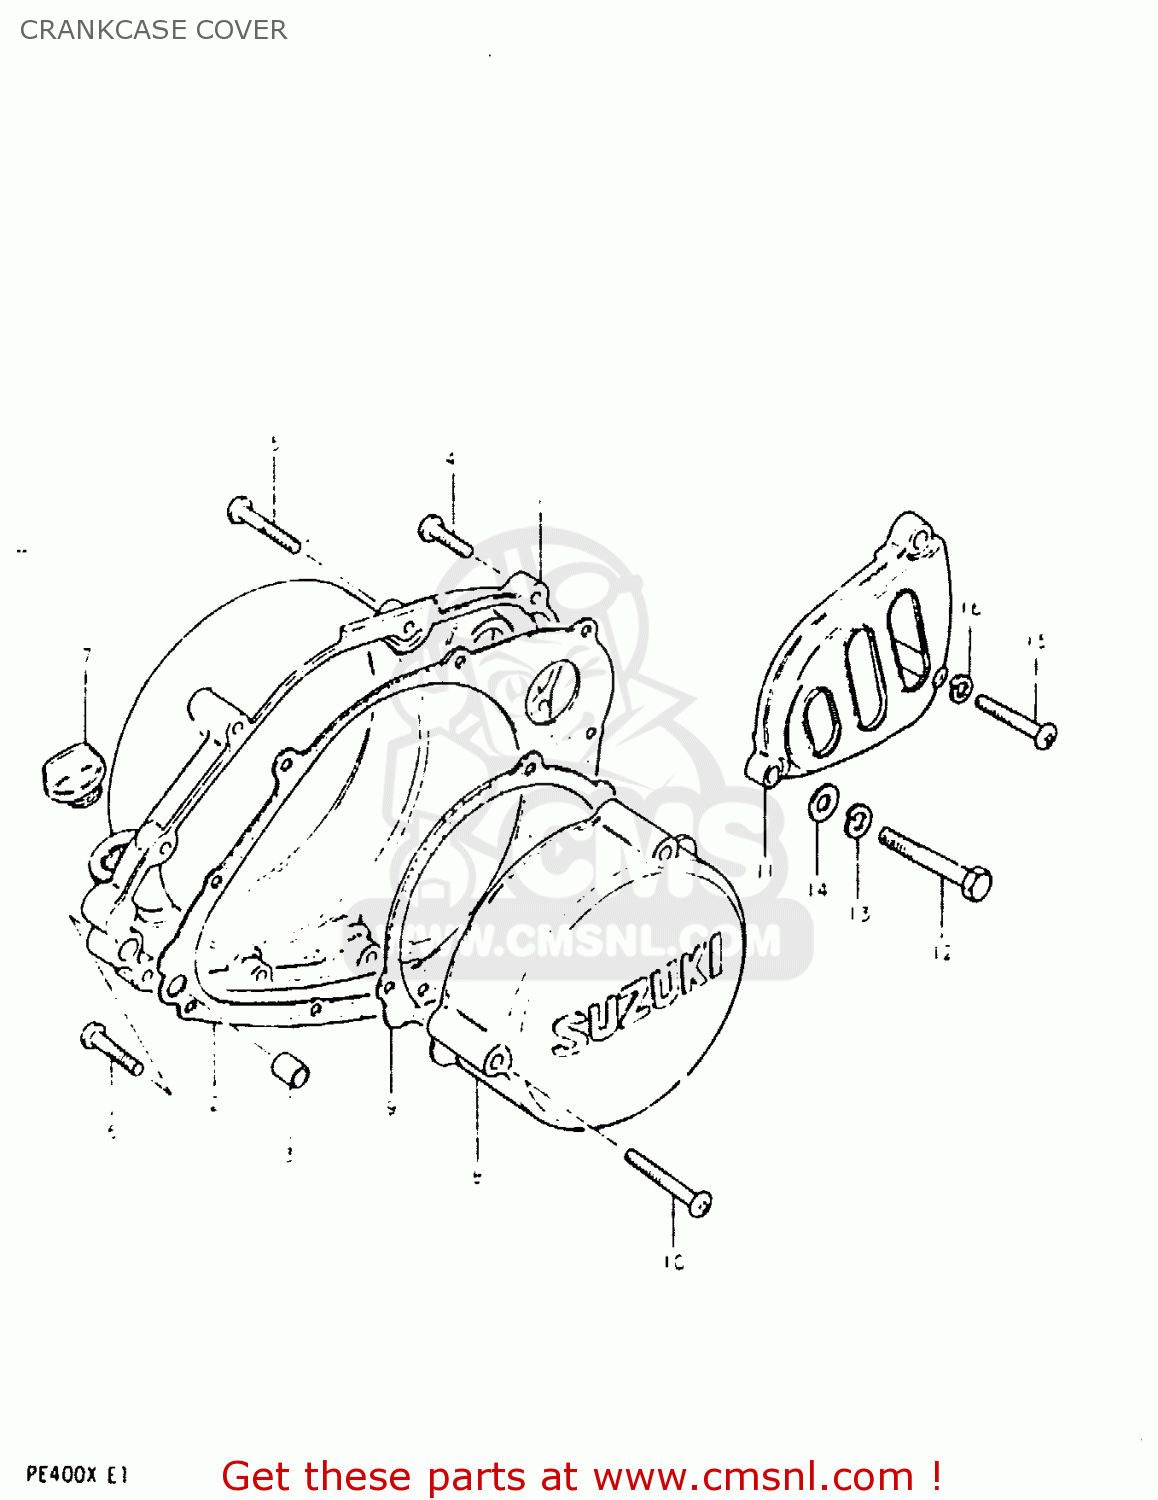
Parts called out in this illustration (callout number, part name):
1	COVER,CLUTCH
2	GASKET,CLUTCH COVER (MCA)
3	PIN
4	SCREW
5	SCREW 6X30
6	SCREW (6X45)
7	PLUG,OIL FILTER
8	COVER,MAGNETO
9	GASKET,MAGNETO COVER (NAS)
10	SCREW
11	COVER,ENGINE SPROCKET
12	BOLT 8X55
13	LOCK WASHER
14	WASHER
15	SCREW
16	LOCK WASHER
